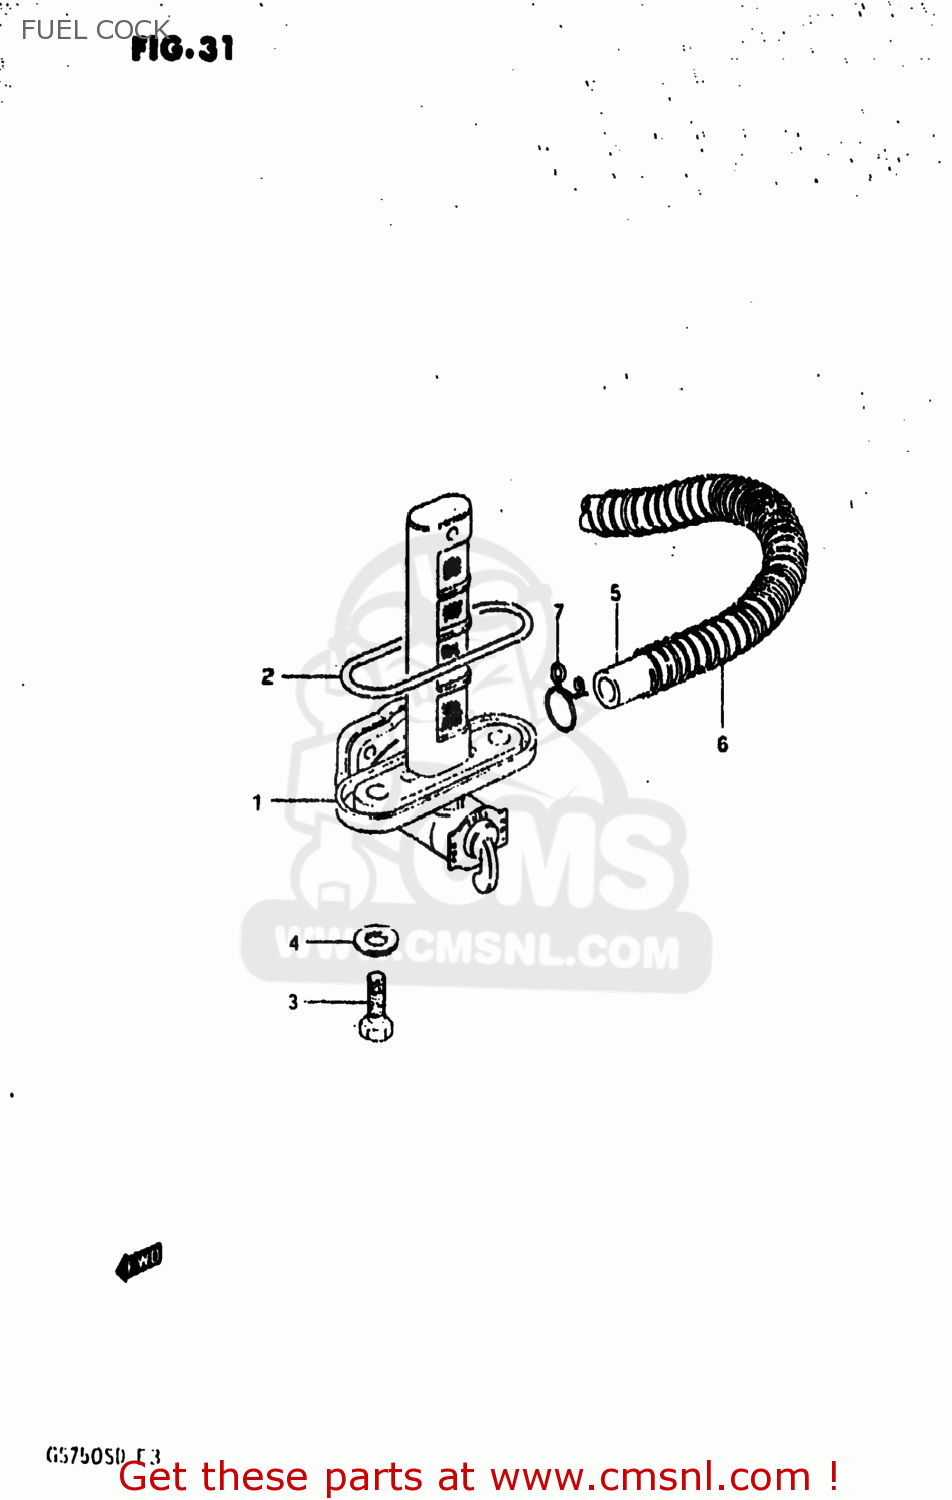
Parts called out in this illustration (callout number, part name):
1	COCK ASSEMBLY,FUEL
2	O RING
3	BOLT(6X20)
4	GASKET
5	HOSE
6	SPRING
7	CLIP
